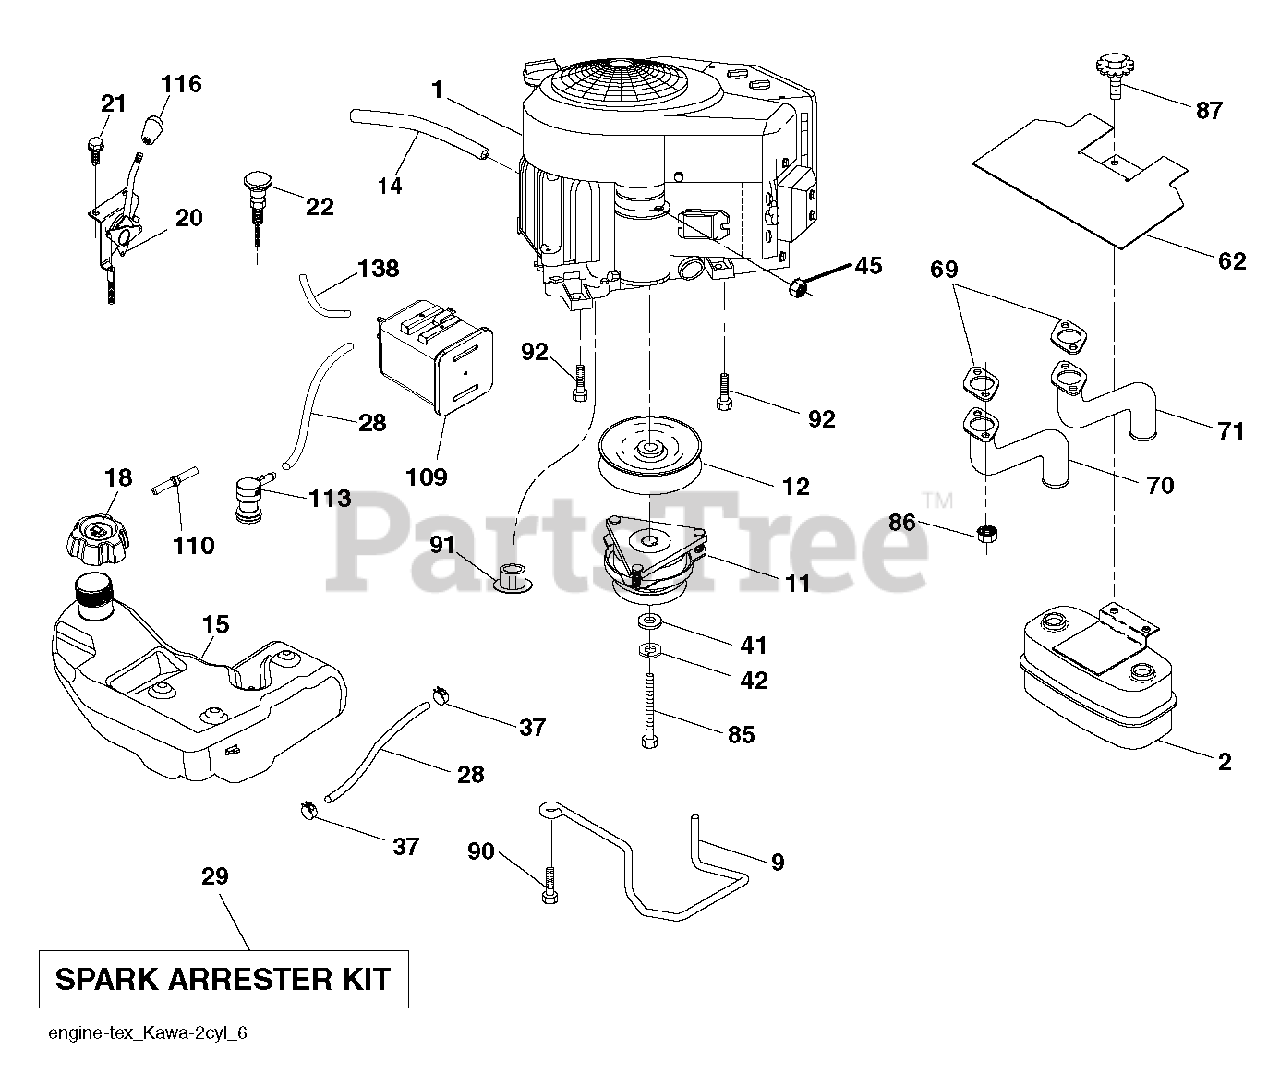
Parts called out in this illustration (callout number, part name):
2	MUFFLER ASSM
9	KEEPER.BELT.ENGINE.4.2
11	CLUTCH ELECTRIC
12	PULLEY ENGINE
14	TUBE, DRAIN OIL ASM.
20	CONTROL THROTTLE
21	SCREW.#10 X 0.750.BOS THREAD
22	CONTROL CHOKE
28	LINE.FUEL.64"REAR.EMIS
29	ARRESTER SPARK (OPTIONAL)
37	HOSE CLAMP
42	LOCKWASHER
62	SHIELD.HEAT.MUFFLER
70	TUBE.EXHAUST
71	TUBE.EXHAUST
85	BOLT HEX 7/16-20 X 3.75 GR. 5
87	BOLT.5/16-18UNCX1.W/SE
90	SCREW 3/8-16X1
91	BUSHING.1.375OD
92	SCREW 3/8-16X1
109	CANNISTER, CARBON
113	VALVE.SLANT.CARTRDG.
116	KNOB SOFT TOUCH
